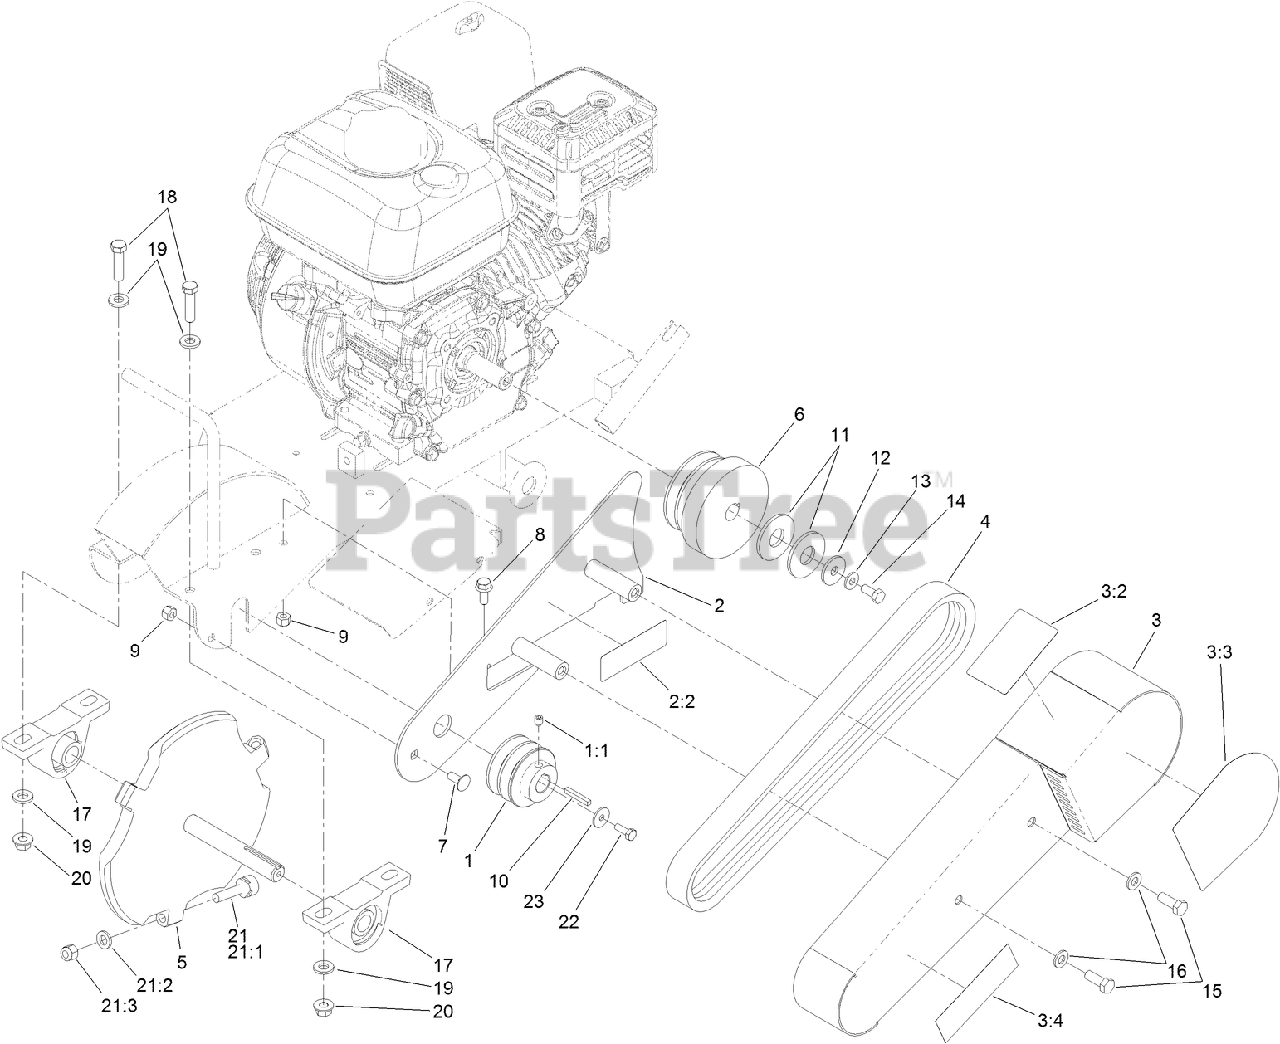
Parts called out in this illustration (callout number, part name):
1	PULLEY-FRONT
1:1	SCREW-HSH
2	PLATE-GUARD, INNER
2:2	DECAL-WARNING
3	BELT GUARD ASM
3:2	DECAL-CAUTION
4	BELT-V, BANDED
5	WHEEL-GRINDER
6	CLUTCH-CENTRIFUGAL
7	SCREW-CARR
8	SCREW-HHF
9	NUT-LOCK, NI
10	KEY-SQUARE
11	WASHER-FLAT
12	WASHER
13	WASHER-FLAT
14	SCREW-HH
15	SCREW-HH
16	WASHER-FLAT
17	BEARING
18	SCREW-HH
19	WASHER-HARDENED
20	NUT-FLANGE, LOCK
21	GRINDER TOOTH KIT (3-PACK)
21:1	TOOTH-GRINDER
21:2	WASHER-HARDENED
21:3	NUT-LOCK
22	SCREW-HH
23	WASHER
